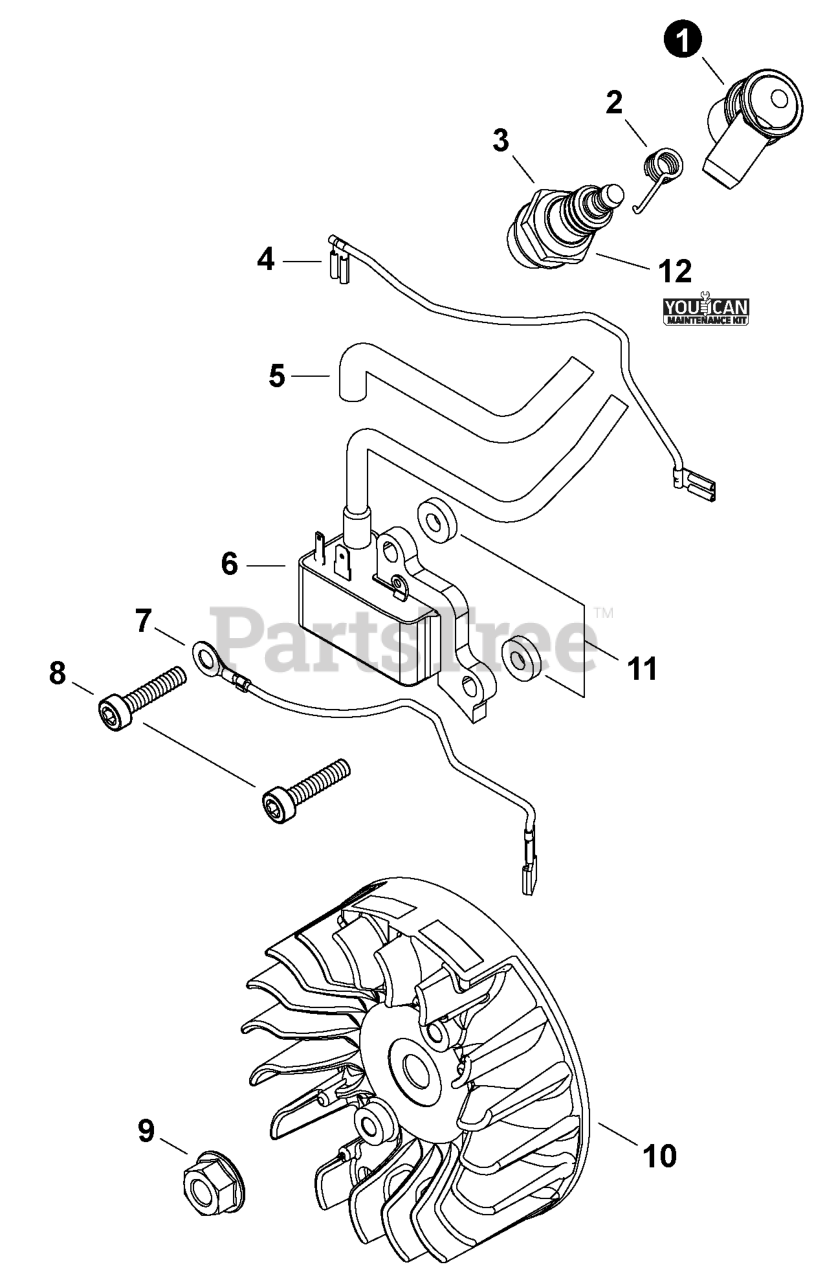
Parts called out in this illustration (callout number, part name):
1	CAP, SPARK PLUG
2	TERMINAL, SPARK PLUG
3	SPARK PLUG - BPMR8Y
4	LEAD - IGNITION
5	TUBE, INSULATOR
6	COIL, IGNITION
7	LEAD - GROUND
8	BOLT, TORX 5x20
9	NUT, FLANGE M8
10	FLYWHEEL
11	WASHER 5.2x12x3
12	TUNE-UP KIT - YOUCANT
